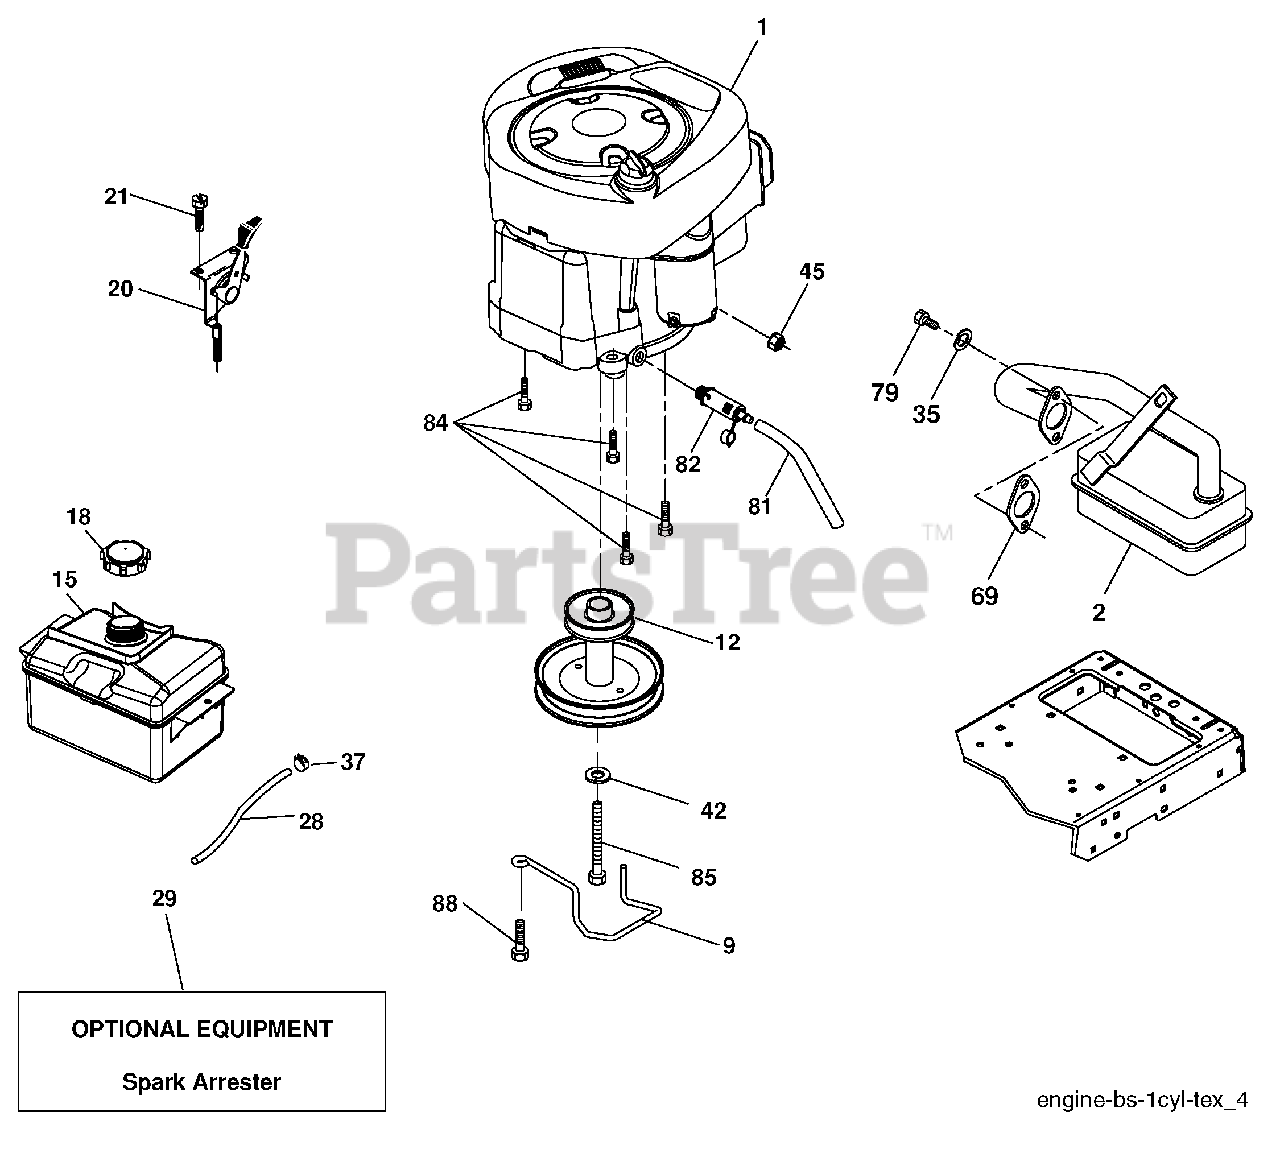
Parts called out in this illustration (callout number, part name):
2	Muffl er
9	Keeper Belt Engine
12	Pulley Engine
15	Tank Fuel
18	Cap Asm
20	Control Throttle/Choke
21	Screw 10 x 3/4 Single Lead-Hex
28	Fuel Line
29	Spark Arrester Kit
35	Washer Split
37	Clamp Hose
42	Washer Lock 7/16
45	Nut Keps Hex 1/4-20 unc
69	Gasket
79	Screw Socket Head 5/16-18 x .75
81	Tube Drain Oil Easy
82	Plug Drain Oil
84	Screw 3/8-16 x 1-1/4
85	Bolt Hex 7/16-20 x 4 x Gr. 5-1.5
88	Screw 3/8-16 x 1
